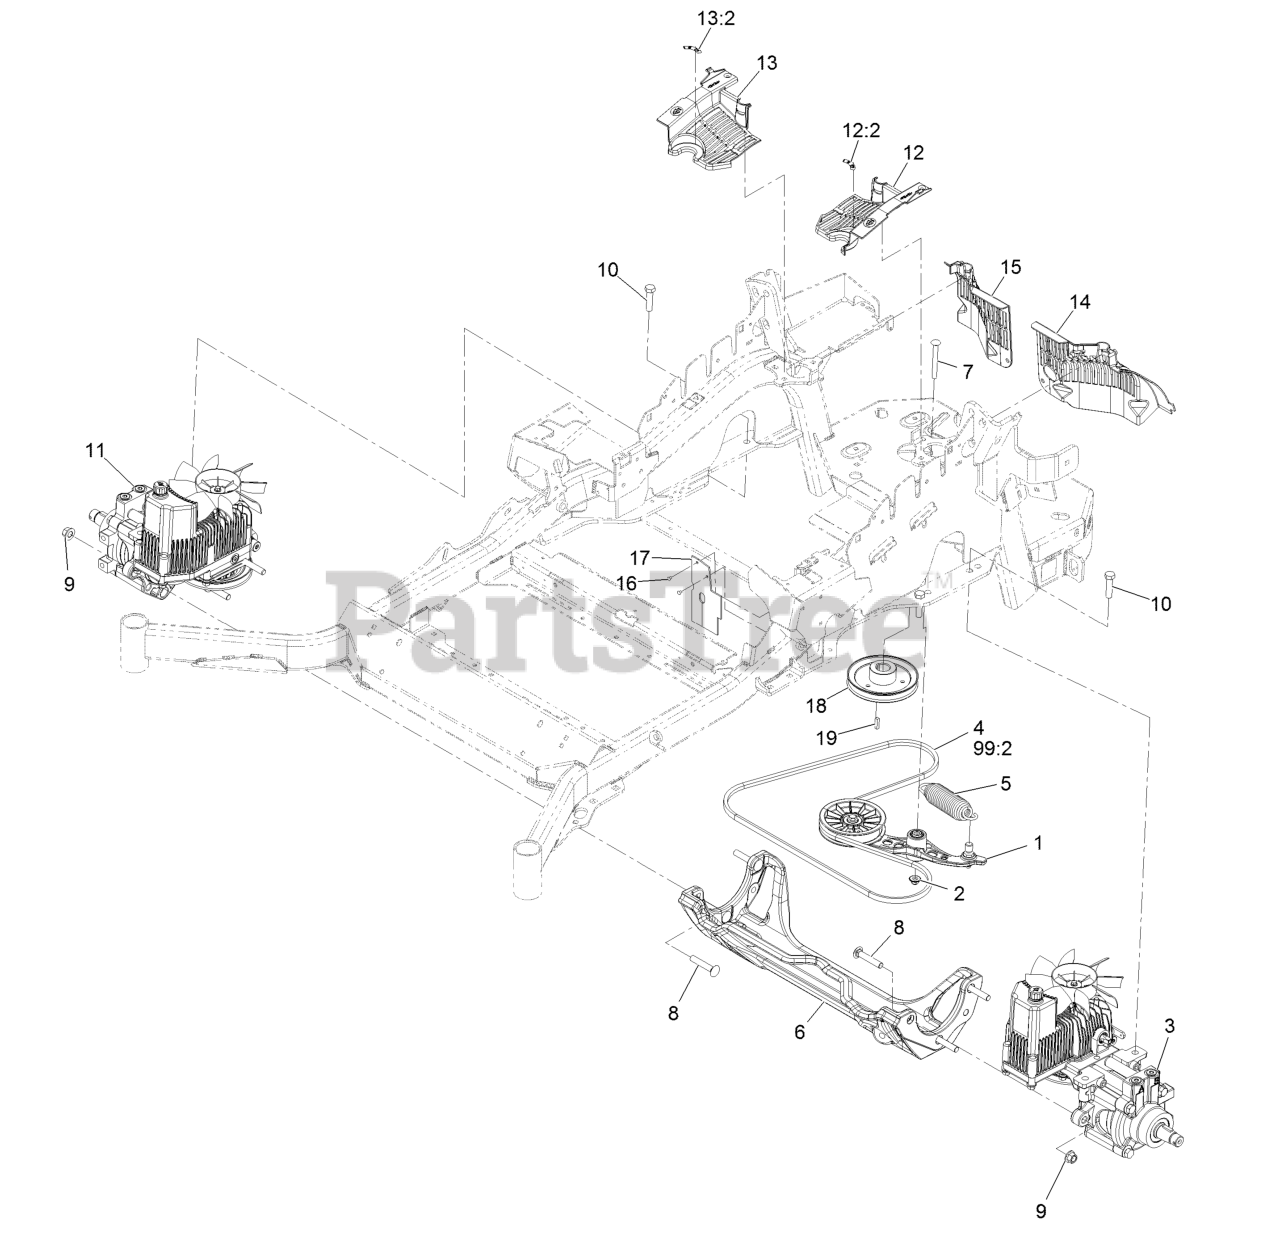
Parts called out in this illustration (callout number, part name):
1	PUMP IDLER ASM
2	Nut-Nyloc 3/8-16 Flg
3	LH HYDRO ASM (16CC W/ SHO
4	BELT
5	SPRING-EXTENSION
6	CRADLE-HYDRO
7	BOLT-SHOULDER, CARRIAGE 3/8-16 X 3 1/2
8	SCREW-CARR
9	Nut-Lock 1/2-13
10	SCREW-HH
11	RH HYDRO ASM (16CC W/ SHO
12	LH HYDRO GUARD ASM
12:2	DECAL-OIL, HYDRO
13	RH HYDRO GUARD ASM
13:2	DECAL-OIL, HYDRO
14	GUARD-HYDRO, REAR (LH)
15	GUARD-HYDRO, REAR (RH)
16	RIVET-POP
17	DEFLECTOR-AIR FLOW
18	SHEAVE
99:2	BELT
